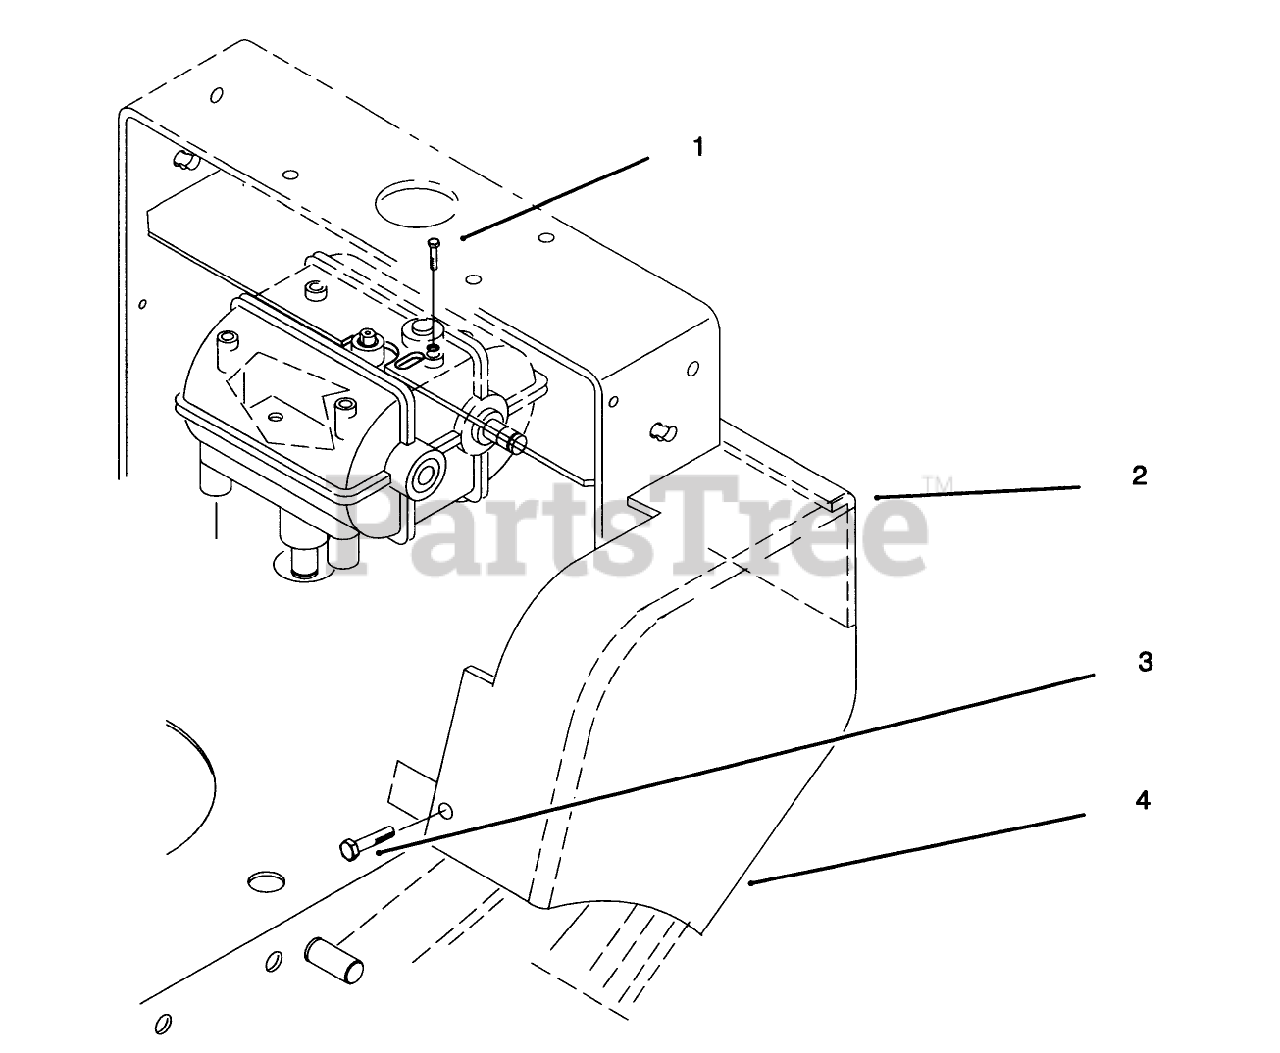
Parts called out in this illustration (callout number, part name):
1	SCREW-HWHTF
2	Guard-Shaft Trans.
3	SCREW
4	GUARD - LH BELT
